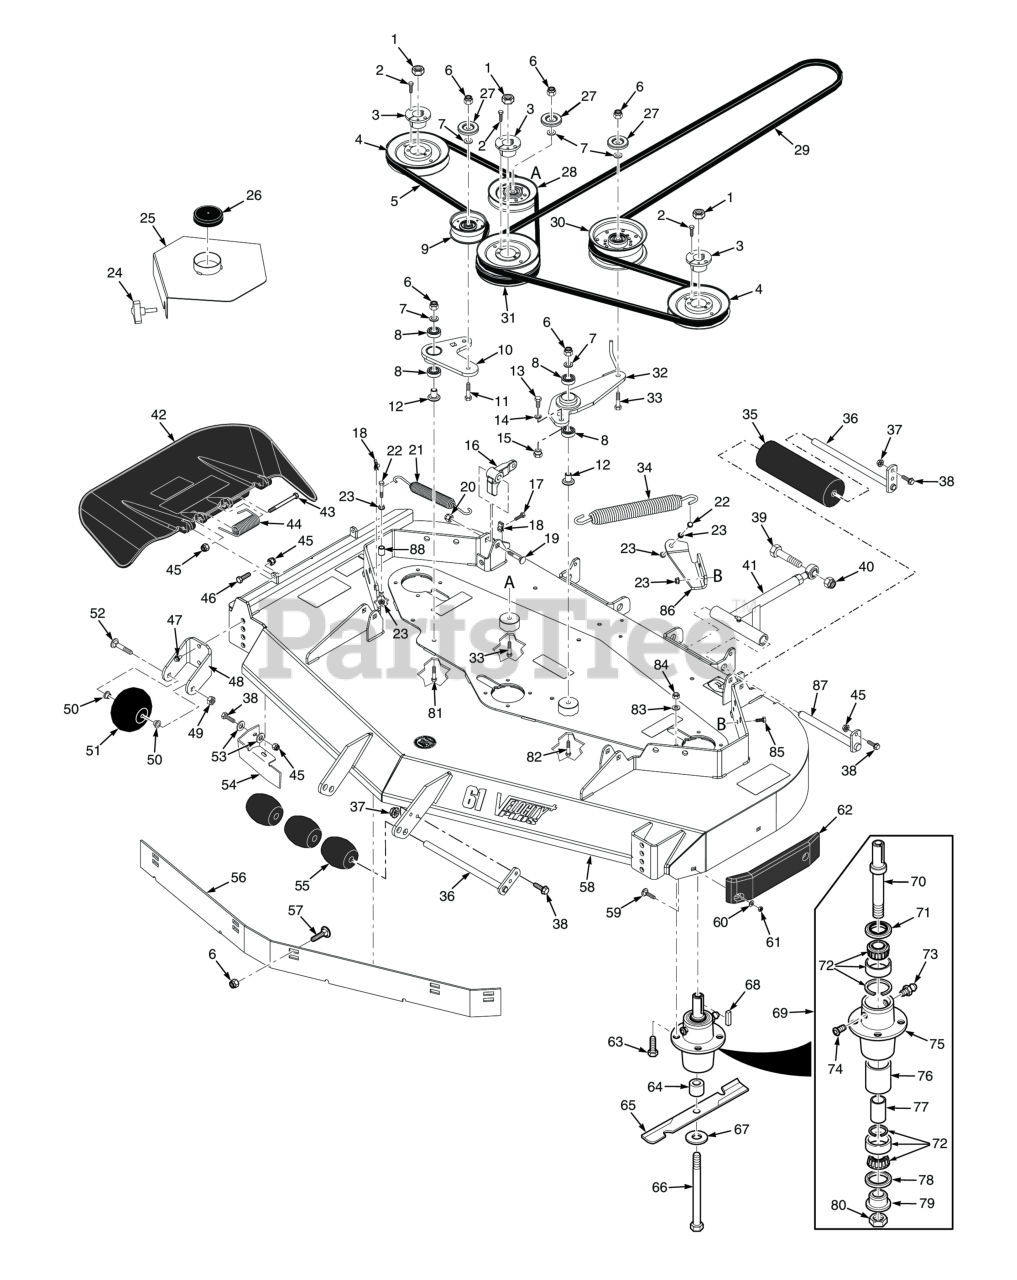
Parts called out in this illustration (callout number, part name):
1	Hex Locknut, Elastic Stop, 3/8-16
2	Bolt, Hex Head 1/4-20 x 1" Grade 8 Black
3	Hub, Tapered 1-1/8" Bore
4	Pulley, Tapered Bore 6.33" Dia.
5	Belt, Deck Drive R.H.
6	HEX NUT, ELASTIC STOP LOCK, 3/8-16
7	Flatwasher, 3/8 (.391 x .938 x .105 HD) Grade 8
8	BEARINGS, BALL, NEUTRAL RETURN
9	Pulley, 3-1/2" Dia.
10	Idler Arm
11	Capscrew, Hex Head 3/8-16 x 2-1/2"
12	Pivot, Idler Short
13	Bolt, Hex Head 7/16-14 x 1"
14	Lockwasher, 7/16� Spring
15	Boss, Spring Anchor - LH
16	Lever, Deck Level
17	Bolt, Hex Head 3/8-16 x 2" Special Lock
18	U-Nut, 3/8-16 (short)
19	Bolt, Carriage 7/16-14 x 2-1/4"
20	HEX LOCKNUT, ELASTIC STOP, 7/16-14
21	Spring, RH Deck Drive
22	Bolt, Hex Head 3/8-16 x 1-1/2" Grade 8 Black
23	NUT, 3/8-16 SERRATED FLANGE HEX HEAD
24	Knob, w/stud 3/8-16 x 1-1/4"
25	Belt Cover Weldment (incl. #26)
27	Quick Pin, 5/16" Dia.
28	IDLER PULLEY, "V" GROOVE
29	BELT, DECK DRIVE - SMTC-61V
30	Pulley, Idler 5" Dia.
31	Pulley, Double Groove 6.33" Dia.
32	Idler Arm
33	Bolt, Hex Head 3/8-16 x 3" - 52"
34	Spring, L.H. Deck Drive
35	Wheel, Anti-ScalpRelief Fitting, Tapered Spindle
36	Shaft Weldment, Guide Roller
37	Nut, Flange Head Elastic Stop 5/16-18
38	Bolt, Heax Head 5/16-18 x 1" (48V / 52V)
39	BOLT, HEX HEAD 5/8-11 X 4-1/2"
40	HEX LOCKNUT, ELASTIC STOP, 5/8-11
41	Push Arm (Includes 64,60,62)
42	Discharge Chute Advantage - Large
43	Bolt, 5/16-18 x 4-3/4" Hex Head
44	Spring, Discharge Chute
45	HEX NUT, ELASTIC STOP LOCK, 5/16-18
46	Bolt, Hex Head 5/16-18 x 1-1/2" - Front
47	Capscrew, 3/8-16 x 1.0" Serrated Flange Hex Hd
48	Bracket, Anti-Scalp Wheel
49	Bolt, Hex Head 3/8-16 x 1" Ser. Flg.
50	Bushing, .376" I.D. Oilite
51	Bolt, Carriage 3/8-16 x 4"
52	Bolt, Hex Head 3/8-16 x 3-1/2"
53	Flatwasher, 5/16-.375 x .875 x .083 (35BV & 37BV-EFI)
54	Turbo Baffle, Bolt On
55	Wheel, Anti-Scalp
56	Baffle Custom-Cut, 61V (7-Position)
57	Carriage Bolt, 3/8-16 x 1.0"
58	Cutter Deck Velocity Plus
59	Bolt, 5/16-18 x .75 RHSN Carriage
60	Flatwasher, 5/16-.344 x .688 x .065 (48V / 52V)
61	Nut, Center Lock, 5/16-18(32)
62	Pad, Deck Wear
63	Bolt, Hex Head 5/16-18 x 1-3/4" Grade 8
64	Spacer, Spindle Bottom
65	Cutter Blade, 21" Standard
66	BOLT, HEX HEAD, 5/8-11 X 9-1/2 GR.5
67	Flatwasher, 5/8-.688 x 1-3/4 x .134 HD
68	Key, 1/4 x 1/4 x 2.0"
69	Cutter Spindle Assembly
70	Spindle Shaft, Tapered Brng
71	SEAL, 2.00 O.D. X 1.50 BORE
72	Tapered Bearing Set (Two Bearings W/Race)
73	GREASE FITTING, STR. 1/4-28 SELF TAP.
74	RELIEF FITTING, TAPERED BEARING SPINDLE
75	Housing, Spindle
76	Spacer, Outside, Cutter Spindle
77	SLEEVE, CUTTER SPINDLE
78	Seal, 2.00" O.D. x 1.625" Bore
79	SPINDLE BUSHING, BOTTOM
80	Nut , Spec ial 1 -1/ 1 6 - 1 8
81	Bolt, Hex Head 3/8-16 x 2-1/4" - 61"
82	Capscrew, Hex Head 3/8-16 x 3.25"
83	Lockwasher, 5/16 (.317 x .586 x .078) Helical Spring
84	Lock Nut, 5/16-18 Elastic Stop Grade 8
85	Bolt, Hex Head, 3/8-16 x 1 Gr. 5
86	Bracket, Spring Anchor
87	Shaft Weldment, Pusharm
88	SPACER, IDLER
